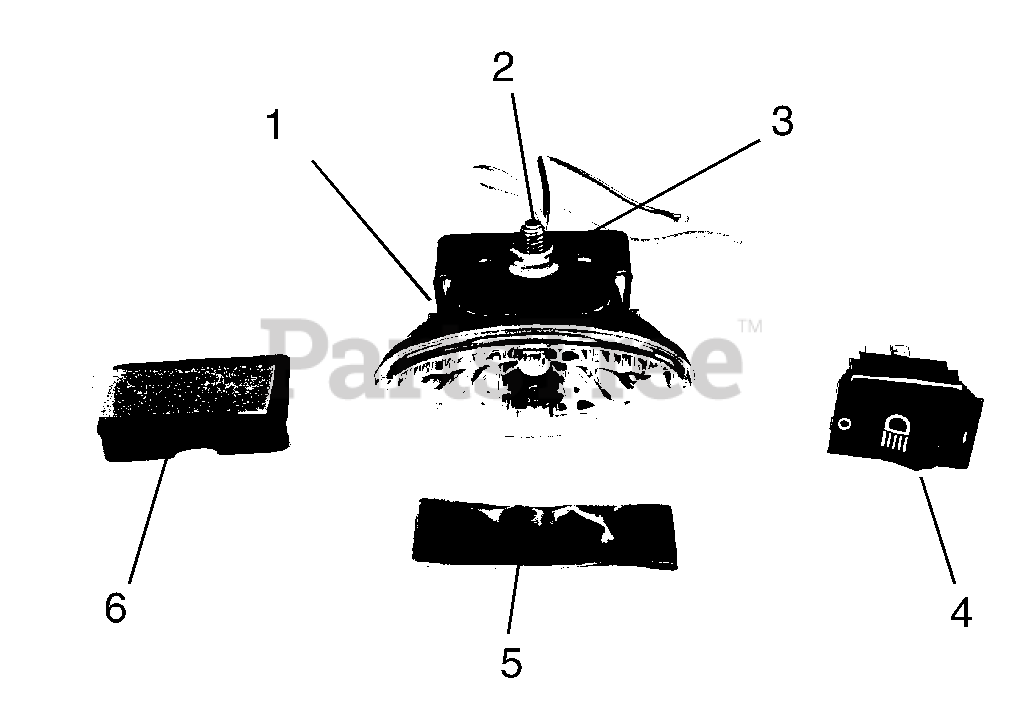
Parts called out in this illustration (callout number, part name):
1	Light Assembly, Consumer Ride-On
2	Round Head Square Neck Bolt, 5/16"-18 x 3/4" Grade 5
3	Spin Lock Flange Nut, 5/16"-18
4	Light Switch
5	Tape, VHB 4941F
6	Spacer
